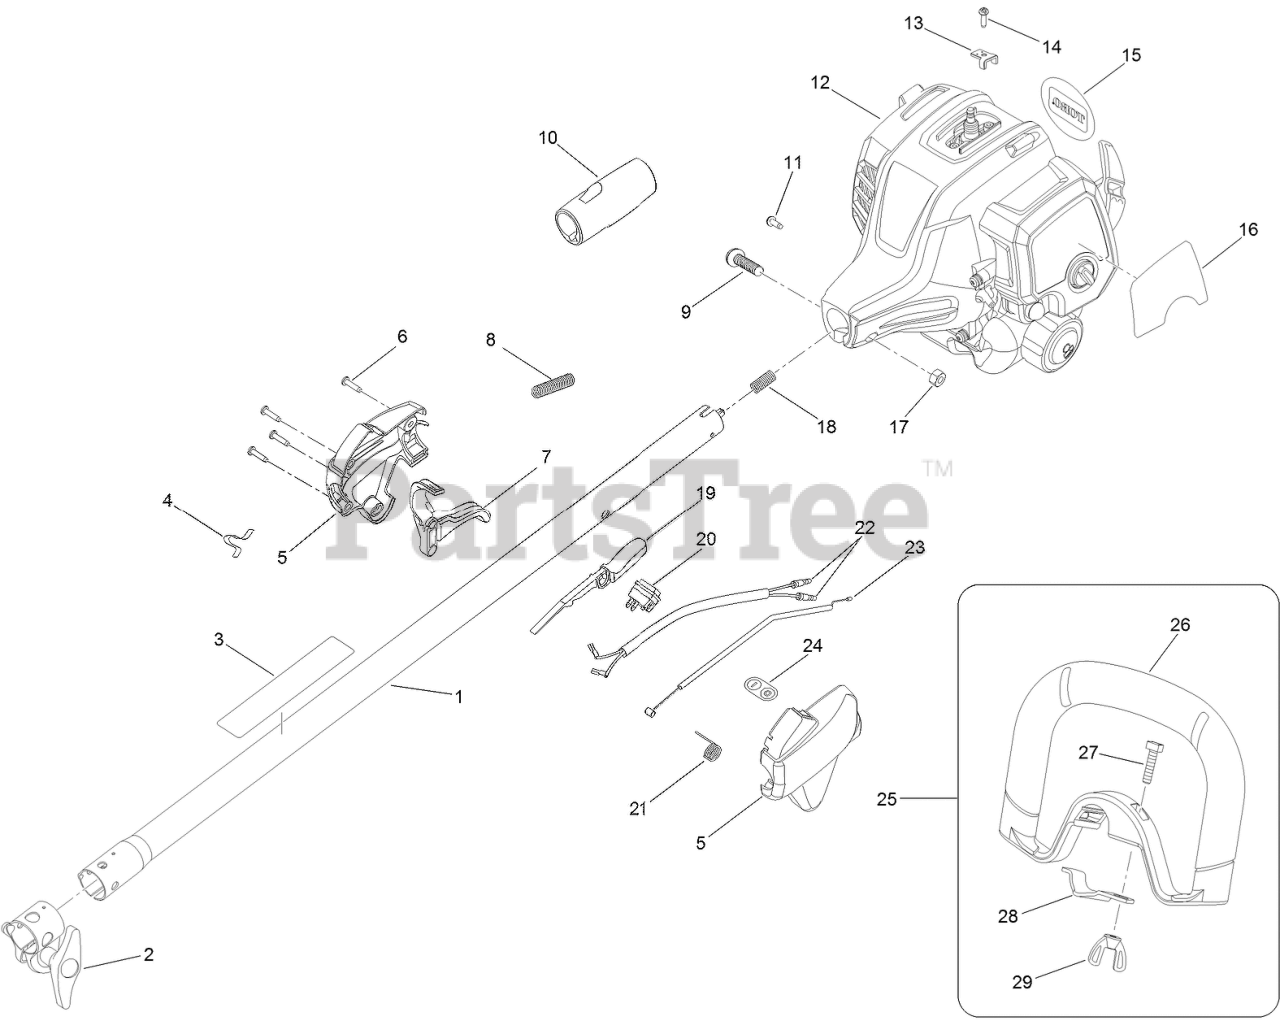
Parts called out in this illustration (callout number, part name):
1	UPPER SHAFT ASM
2	SHAFT CLAMP ASM
3	LABEL-WARNING
4	CLIP-STRAP, SHOULDER
5	CONTROL HANDLE ASM
7	TRIGGER-THROTTLE
8	TUBE-CORRUGATED
10	GRIP-SHAFT, UPPER
12	POWERHEAD ASM
13	CLAMP-CABLE, THROTTLE
15	PLATE-LOGO
16	DECAL-START
17	NUT-HEX
18	SPRING-COMPRESSION
19	TRIGGER-LOCK, THROTTLE
20	SWITCH-ON/STOP
21	SPRING-TRIGGER
22	HARNESS-WIRE
23	CABLE-THROTTLE
24	LABEL-ON/STOP
25	HANDLE ASM
26	HANDLE-SHAFT, UPPER
28	CLAMP-HANDLE, UPPER SHAFT
29	NUT-WING
